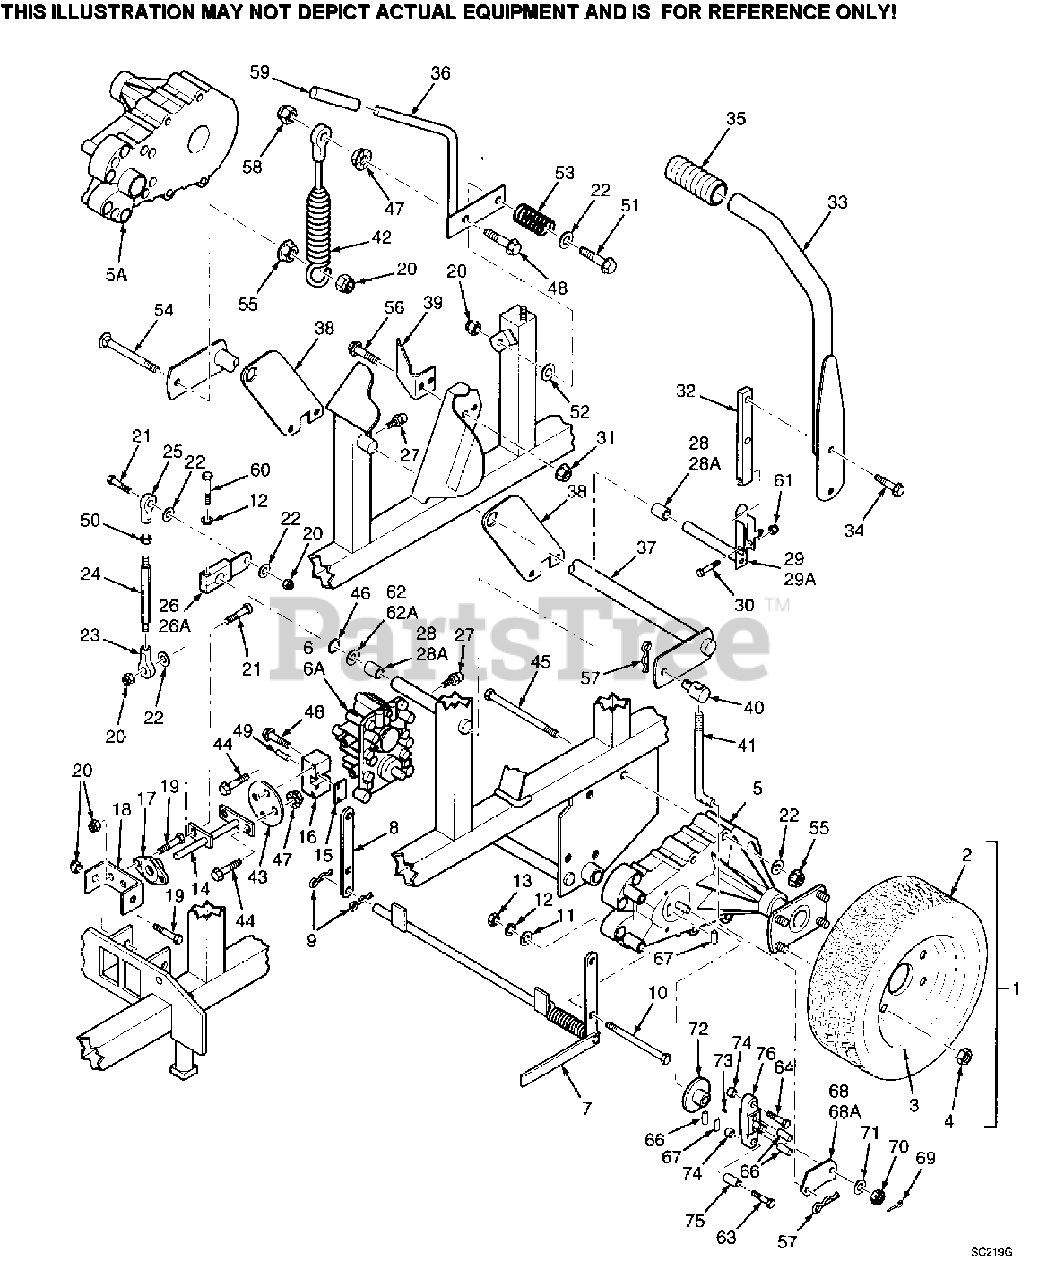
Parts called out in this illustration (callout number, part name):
1	DRIVE WHEEL ASSEMBLY
2	TIRE ONLY
3	RIM ONLY
4	LUG NUT, 1/2-20
5	AXLE, LH(INCLUDES BRAKE LEVER)
5A	AXLE, RH(INCLUDES BRAKE LEVER)
6	PUMP, LH
6A	PUMP, RH
7	DUMP VALVE, LEVER WELDMENT
8	BRACKET, MOUNTING
9	HAIR PIN
10	BOLT, HEX HEAD 5/16-18 X 5"
14	PUMP WELDMENT SHAFT
15	CLAMP PLATE
16	BLOCK, PUMP CONTROL
17	BUSHING, SELF ALIGN
18	BRACKET, BEARING
22	FLATWASHER, 3/8" SPECIAL
23	BALL JOINT, LH THREAD
24	LINK, TURNBUCKLE
25	BALL JOINT, RH THREAD
26	LEVER, PUMP TRANSFER LH
26A	LEVER, PUMP TRANSFER RH
27	GREASE FITTING
28	BUSHING, LH
28A	BUSHING, RH
29	CONTROL LEVER, LH
29A	CONTROL LEVER, RH
31	NUT, SERRATED FLANGE HEX 5/16-18
32	BAR CONTROL LEVER
33	CONTROL HANDLE
34	BOLT, SERRATED FLANGE HEX HEAD 3/8-16 X 1"
35	GRIP, CONTROL HANDLE
36	LEVER WELDMENT, PARKING BRAKE
37	CAM WELDMENT, PARKING BRAKE
38	PLATE, PARKING BRAKE
39	LATCH, BRAKE
40	SWIVEL JOINT
41	ROD, BRAKE
42	CABLE ASSEMBLY, PARKING BRAKE
43	PLATE, COUPLER
44	BOLT, SERRATED FLANGE HEX HEAD 1/4-20 X 3/4"
46	RING, RETAINING 3/4" EXTERNAL "E"
47	NUT, SERRATED FLANGE HEX 1/4-20
48	BOLT, SERRATED FLANGE HEX HEAD 1/4-20 X
49	ROLL PIN, 3/16 X 3/4"
52	FLATWASHER, 3/8(.375 X 1-1/2" X 16 GA.)
53	SPRING, BRAKE LEVER
55	NUT, SERRATED FLANGE HEX 3/8-16
56	BOLT, SERRATED FLANGE HEX HEAD 5/16-18 X 3/4"
57	HAIR PIN, 1/16"
59	GRIP, PARKING BRAKE
61	NUT, ELASTIC STOP 5/16-18
62	FLATWASHER, 3/4"
62A	FLATWASHER, 3/4" SPECIAL
63	BOLT, 1/4-20 X 2-1/2 GR. 5 W/PATCH
64	BOLT, 1/4-20 X 1-1/2 GR. 5 W/PATCH
65	PINS, ACTUATING
66	BRAKE PUCK
67	BACKING PLATE
68	ACTUATING LEVER, RH
68A	ACTUATING LEVER, LH
69	PIN, COTTER
70	NUT, CASTLE
71	WASHER
72	DISC
73	KEY, WOODRUFF SPECIAL
74	SPACER, SMALL
75	SPACER, LARGE
76	YOKE BRAKE
